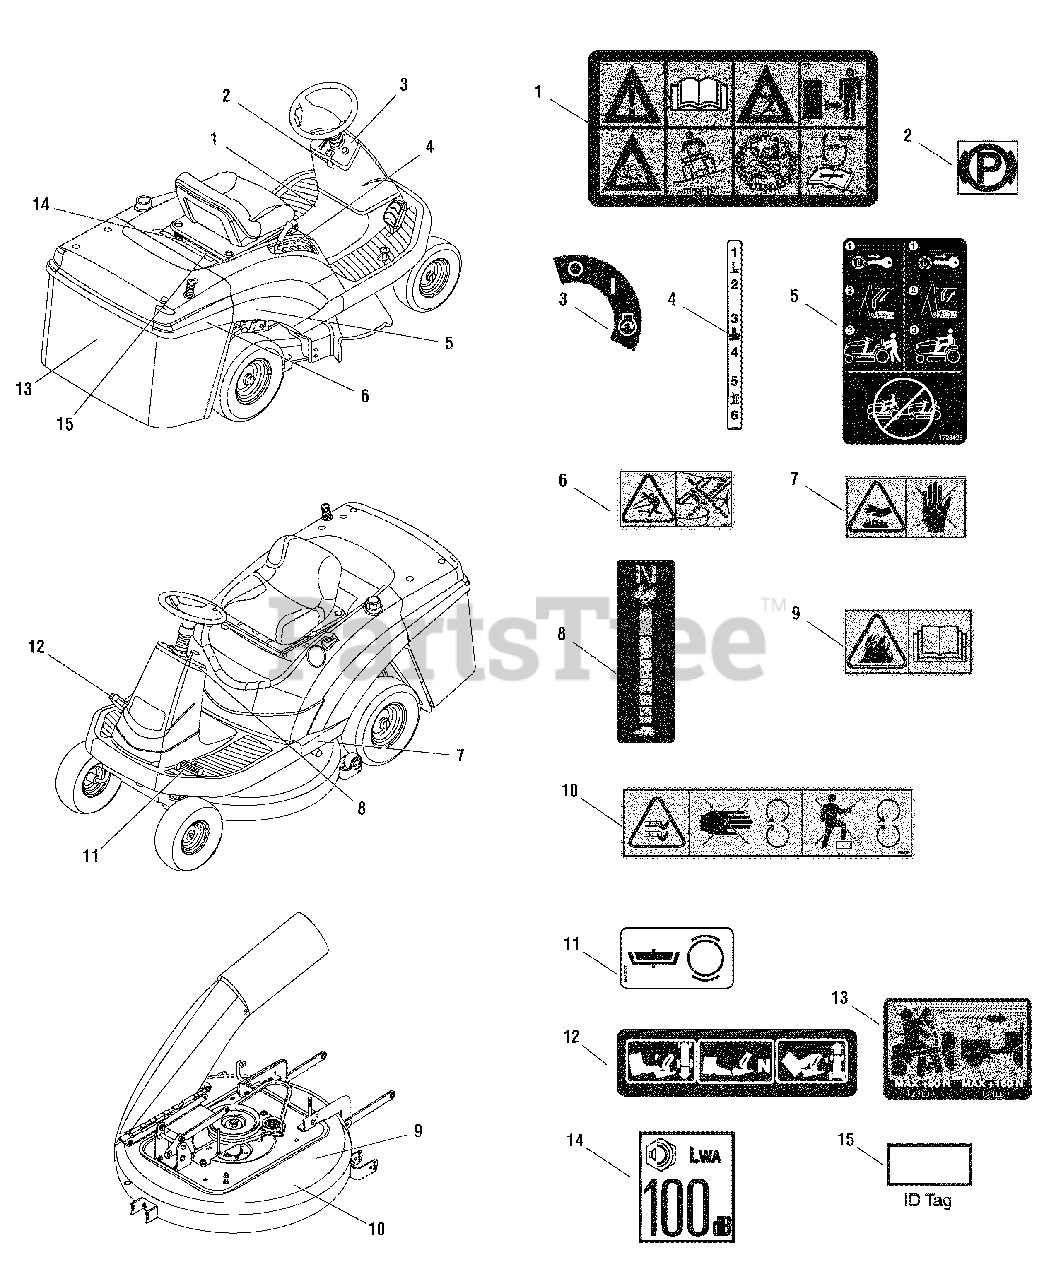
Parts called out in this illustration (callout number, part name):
1	DECAL, Operating Instructions
2	DECAL, Parking Brake
3	DECAL, Ignition Switch
4	DECAL, Cutting Height
5	DECAL, Roll Release
6	DECAL, Discharge Tube
7	DECAL, Hot Surface
8	DECAL, Throttle Control
9	DECAL, Fire Hazard
10	DECAL, Sever Hazard
11	DECAL, Brake/Clutch
12	DECAL, Speed Control
13	DECAL, Draw Bar Load
14	DECAL, Noise Level
15	ID TAG
